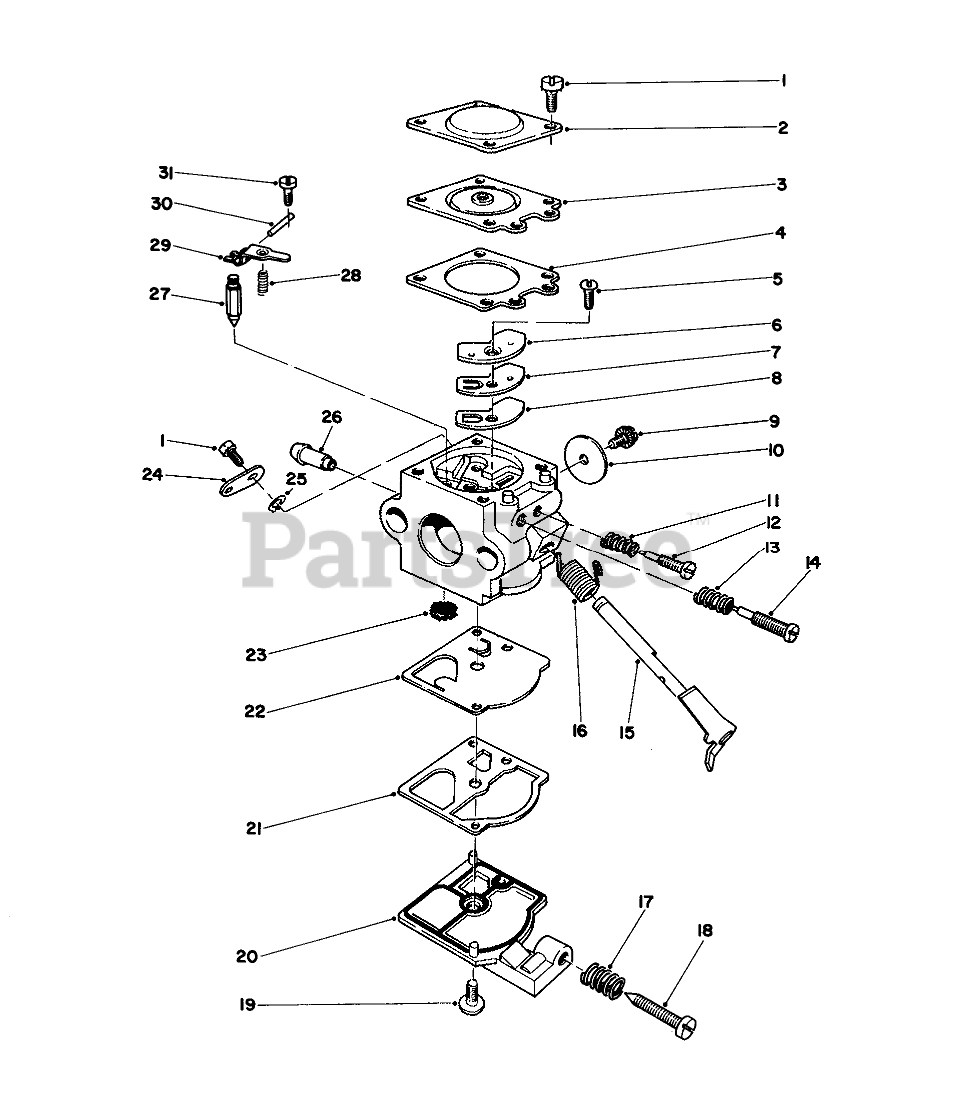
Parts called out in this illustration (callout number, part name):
1	Screw
2	Cover, Diaphragm
3	METERING DIAPHRAGM
4	Gasket, Diaphragm
5	Screw-Circuit Plate
6	Plate, Circuit
7	Diaphragm Circuit Plate
8	Gasket-Circuit Plate
9	Screw-Throttle Valve
10	Valve-Throttle
11	Spring, Needle
12	Needle-Idle
13	Spring, HS Needle
14	Needle, HS
15	Shaft Assembly-Throttle
16	Spring-Throttle Lever
17	Spring-Idle Screw
18	Screw-Idle Adjust
19	Screw
20	Cover-Fuel Pump
21	PUMP GASKET
22	Diaphragm Fuel Pump
23	Inlet Screen
24	Lever-Throttle
25	Ring-Throttle Retainer
26	Fitting Fuel Inlet
27	INLET NEEDLE VALVE
28	METERING LEVER SPRING
29	Lever Metering
30	Metering Lever Pin
31	Screw-Metering Pin
